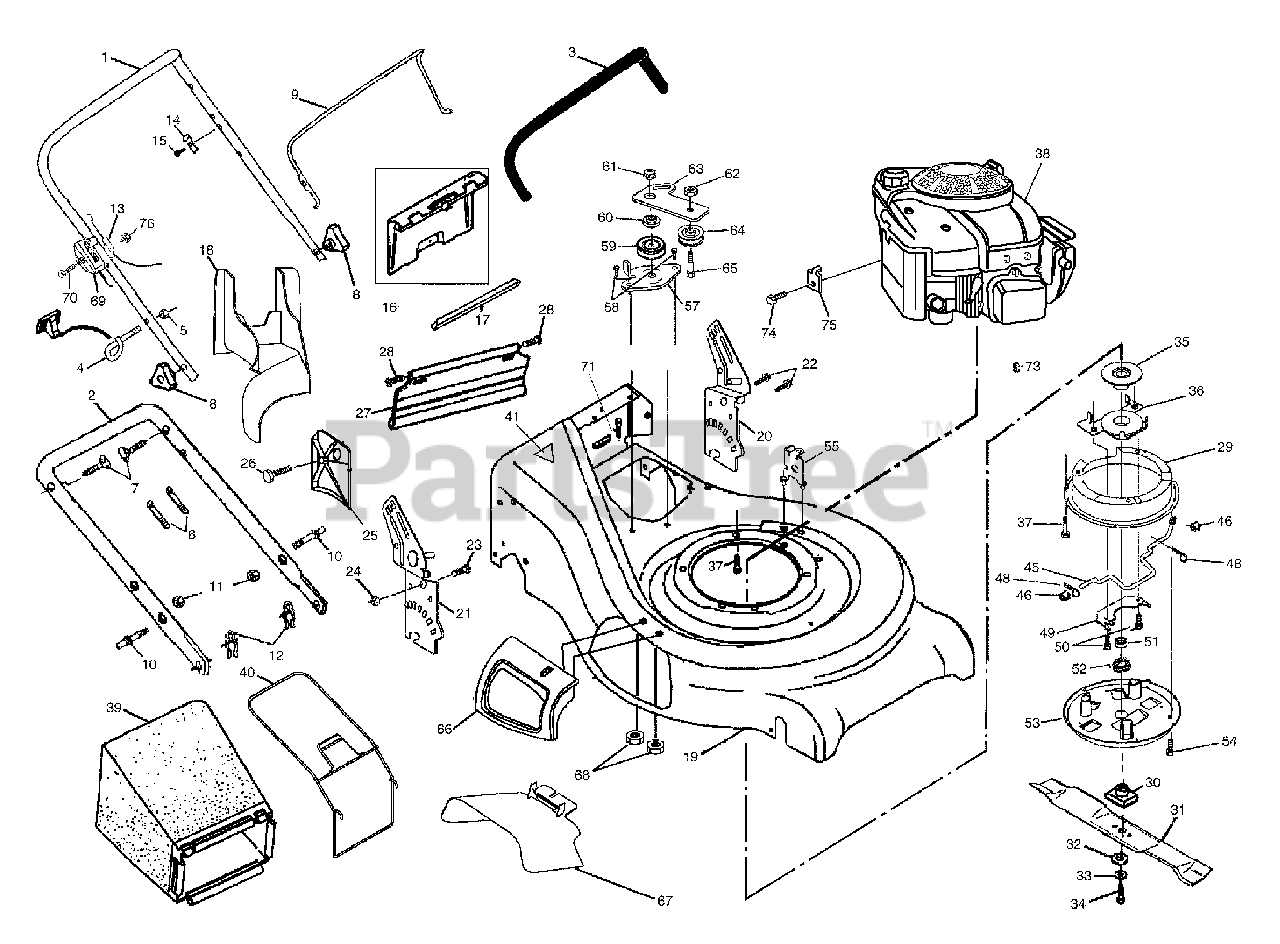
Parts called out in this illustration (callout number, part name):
1	Handle, Upper Dlx Comf.
2	Handle, Lower
3	Grip, Hdl Foam Smooth
4	Guide, Rope, Side
5	Nut, Hex Lockwasher 1/4-20
6	Wire, Tie
7	Bolt, Handle 5/16-18 x 1.75
8	Knob, Handle
9	Bail, Cont. Wire Dlx Comf. Yel
10	Bolt, Sq. Neck
11	Nut, Hex Lockwasher Ins. 5/16-18 UNC
12	Cotter, Hairpin
13	Engine zone control cable
14	Bracket, Upstop
15	Screw, Hex Washer Head Tapping 10-2
16	Kit, Door Rear
17	Seal, Door
18	Plug, Mulcher
19	Kit, Housing
20	Handle, Bracket Asm. Left
21	Handle, Bracket Asm. Right
22	Screw, Hex Wshd
23	Bolt, Hex Head 5/16-18 x 5/8
24	Nut, Hex Lock Wshr 5/16-18
25	Baffle, Side
26	Screw 12 x 5/8
27	Skirt
28	Screw, Hinge 1/4-20 x 1.25
29	Belt Cover, Top
30	Adapter, Blade w/key Longer
31	Blade, 21"
32	Washer, Hardened
33	Lockwasher, Helical Spring 3/8
34	Screw, Hex Head 3/8-24 x 1.38
35	Pulley, Fixed
36	Bearing Support Assy.
37	Bolt, Engine
39	Grass Catcher Bag
40	Grass Catcher Frame
41	Danger Decal
45	Engagement Rod
48	Retainer Clip
49	Clamp
52	Wave Washer
53	Belt Cover, Bottom
54	Screw
55	Cable Support Bracket
57	Bracket Assy.
59	V-Groove Pulley
60	Idler Arm Spacer
61	Flange Nut
62	Locknut
63	Idler Arm
64	Idler Pulley
65	Shoulder Bolt
66	Door Assembly
67	Deflector, Door
69	Throttle Control
70	Screw
73	Hi Pro Key
75	Cable Clamp
76	Nut, Hex 1/4-20
